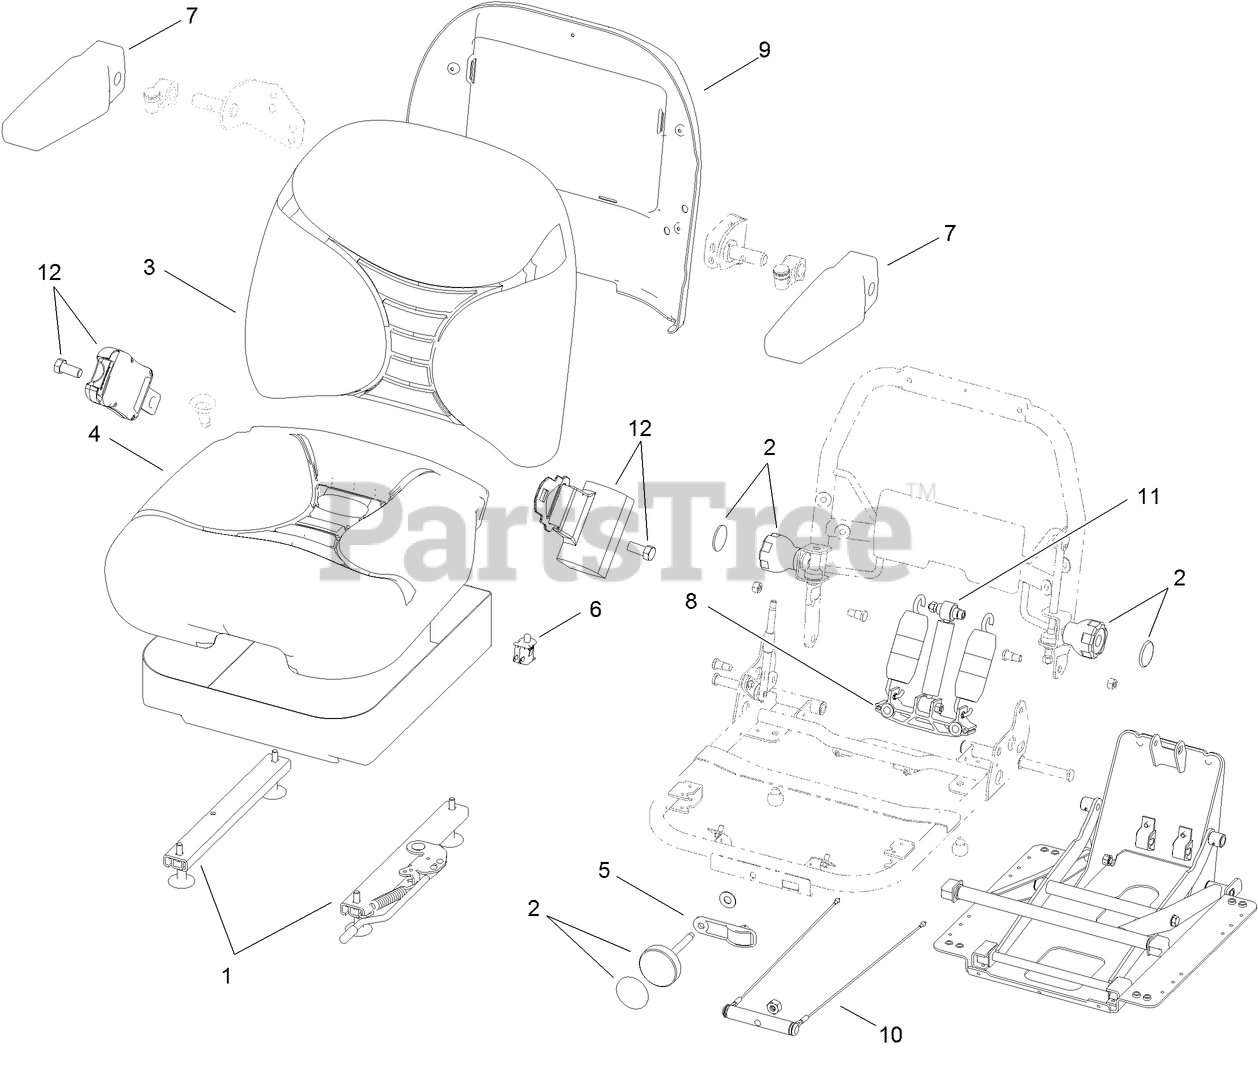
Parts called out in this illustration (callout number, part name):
1	SEAT TRACK KIT
2	Knob Kit
3	Back Cushion Kit
4	Bottom Cushion Kit
5	Weight Indicator Kit
6	SWITCH-BAIL
7	PAD-ARMREST
8	SPRING AND SADDLE KIT
9	BACK PANEL KIT
10	WEIGHT ADJUST KIT
11	SHOCK ABSORBER KIT
12	SEAT BELT KIT (SHORT)
